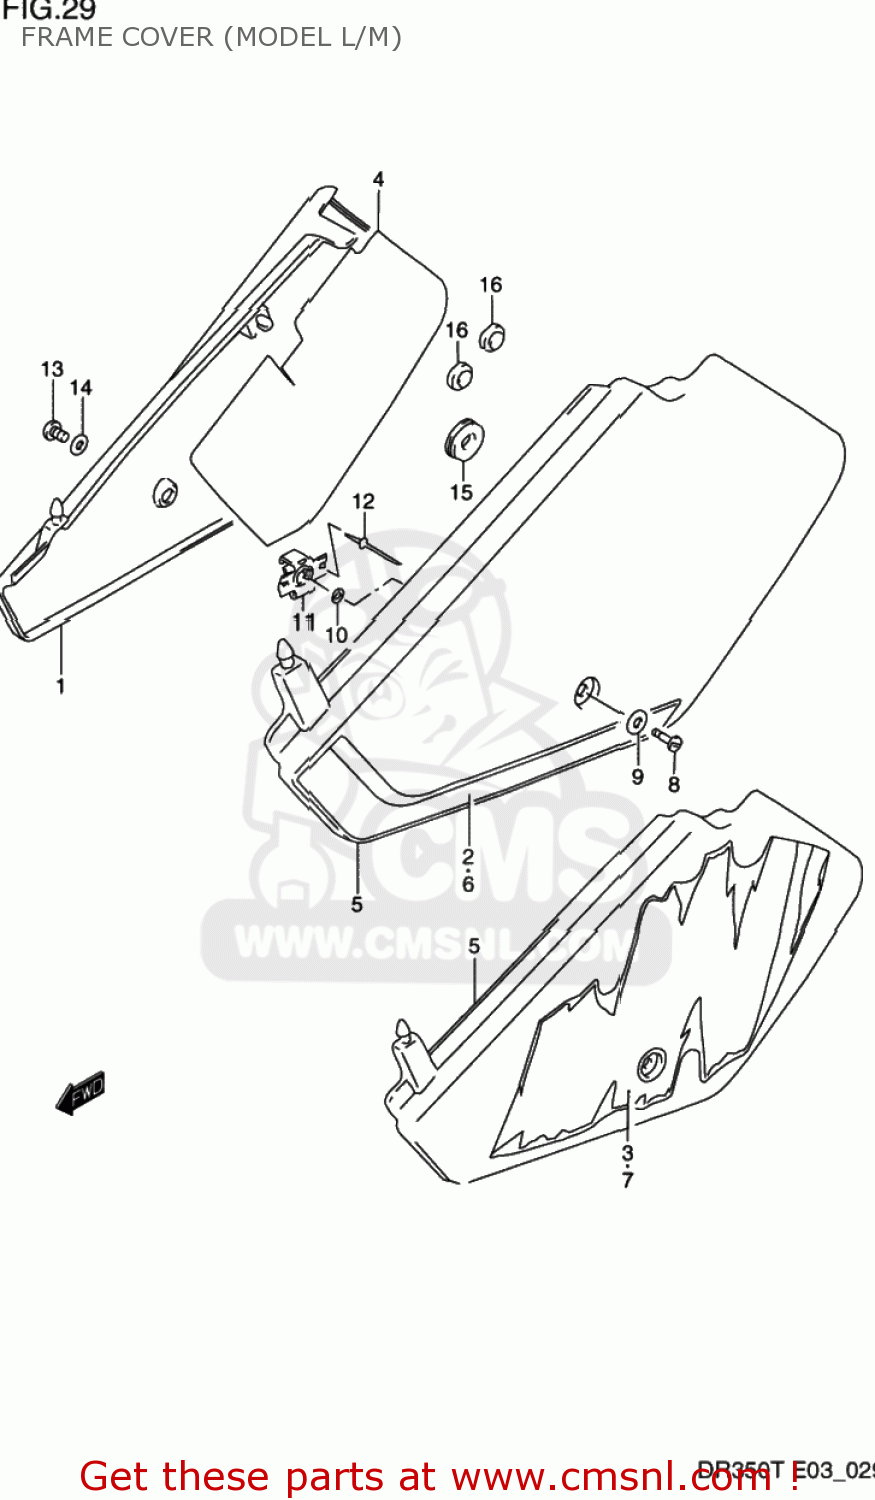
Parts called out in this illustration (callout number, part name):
1	COVER,FRAME,R(WHITE)
2	TAPE,FRAME COVER,RIGHT
3	TAPE,FRAME COVER,RIGHT
4	SHIELD,FRAME COVER,R
5	COVER,FRAME,L(WHITE)
6	TAPE,FRAME COVER,LEFT
7	TAPE,FRAME COVER,LEFT
8	STUD,FRAME COVER,LEFT
9	WASHER(7.2X18X1.6)
10	RETAINER,FRAME COVER STUD,L
11	PLATE,FITING
12	RIVET
13	SCREW
14	WASHER
15	CUSHION
16	CUSHION
